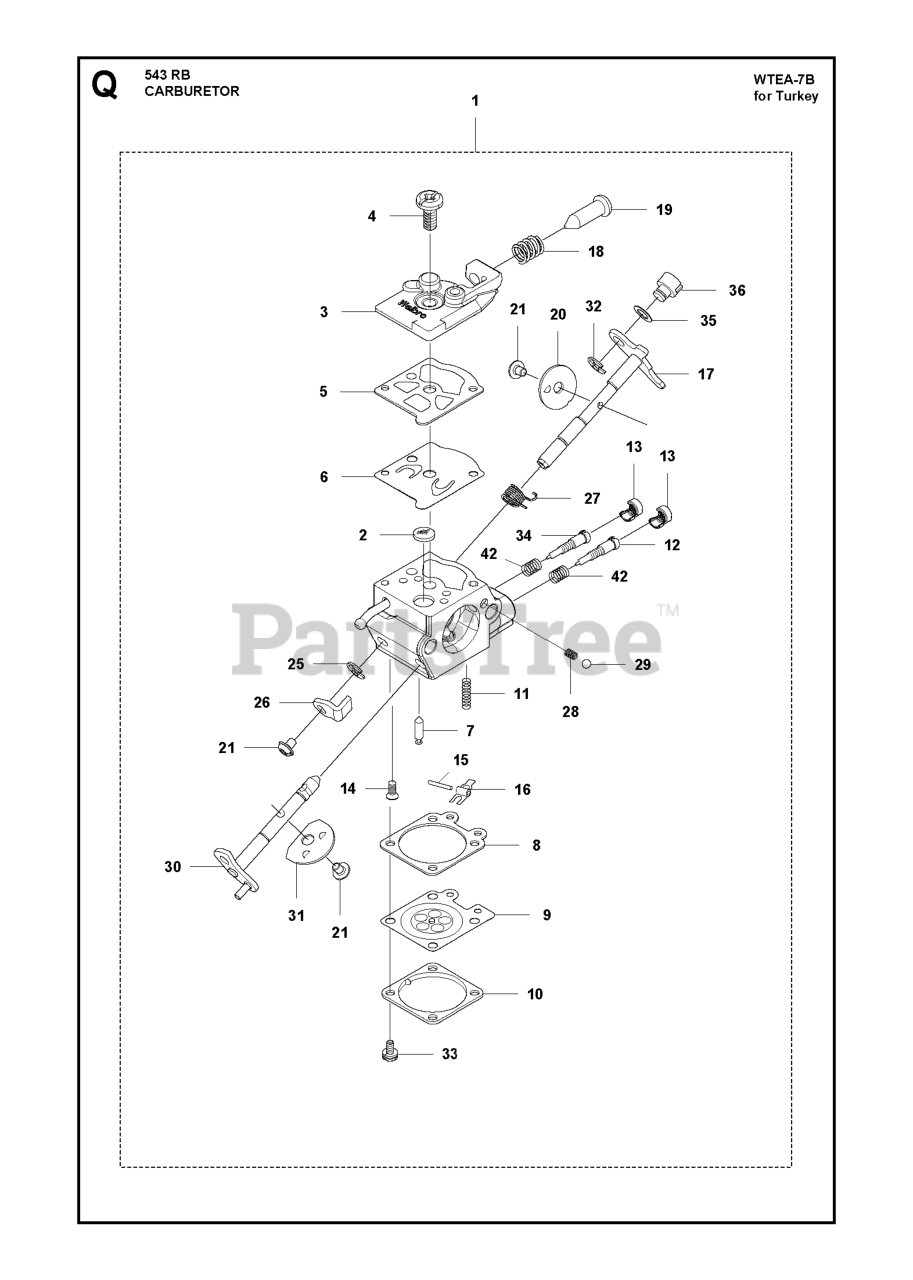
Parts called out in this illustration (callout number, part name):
1	Carburetors
2	SCREEN
3	COVER
4	SCREW
5	GASKET
6	DIAPHRAGM
7	VALVE INLET
8	GASKET
9	DIAPHRAGM
10	COVER
11	SPRING
12	NEEDLE H
13	CAP LIMITER
14	SCREW
15	PIN
16	LEVER
17	SHAFT ASSY THROTTLE
18	SPRING
19	SCREW, IDLE
20	VALVE, THROTTLE
21	SCREW
25	E-RING
26	LEVER THROTTLE
27	SPRING
28	CHOKE SPRING
29	BALL
30	SHAFT ASSY CHOKE
31	VALVE CHOKE
32	RING
33	SCREW ASSY
34	NEEDLE L
35	WASHER
36	SWIVEL
42	SPRING
